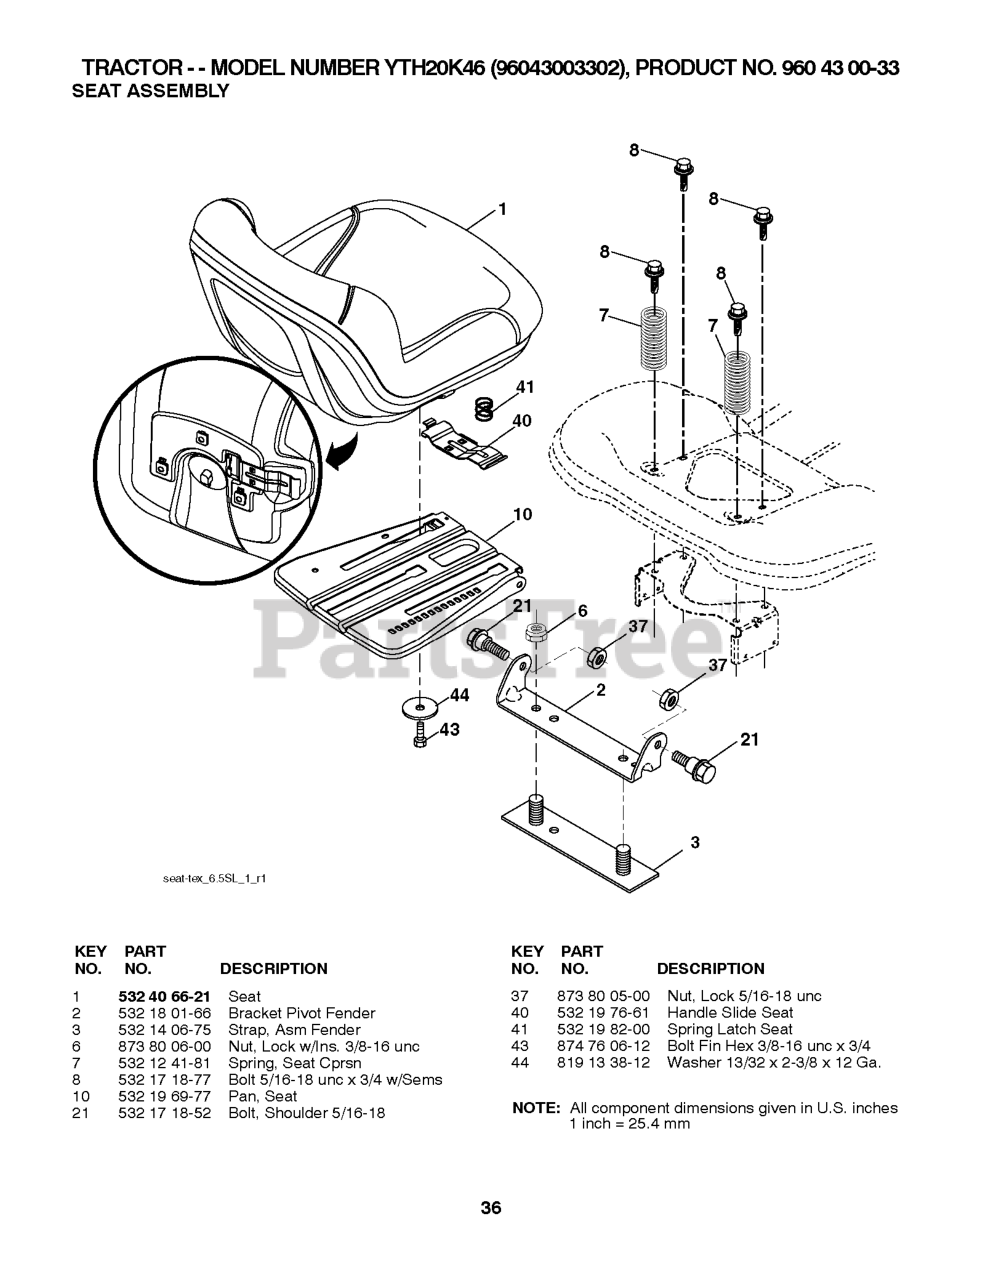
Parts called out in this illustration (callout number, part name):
1	SEAT - GREY
2	BRKT.PIVOT.FENDER
3	STRAP
6	NUT
7	SPRING COMPRESSION
8	BOLT.5/16-18UNCX3/4 W/SEMS.BLK
10	PAN.ASM.SEAT.3PT
21	BOLT.SHOULDER.5/16-18
37	NUT.71038.31-18.HEX.NYLOCK
40	HANDLE.SLIDE.SEAT.TEX.BLACK
41	SPRING.LATCH.SEAT.TEX
44	WASHER 13/32 X 2-3/8 X 12GA
